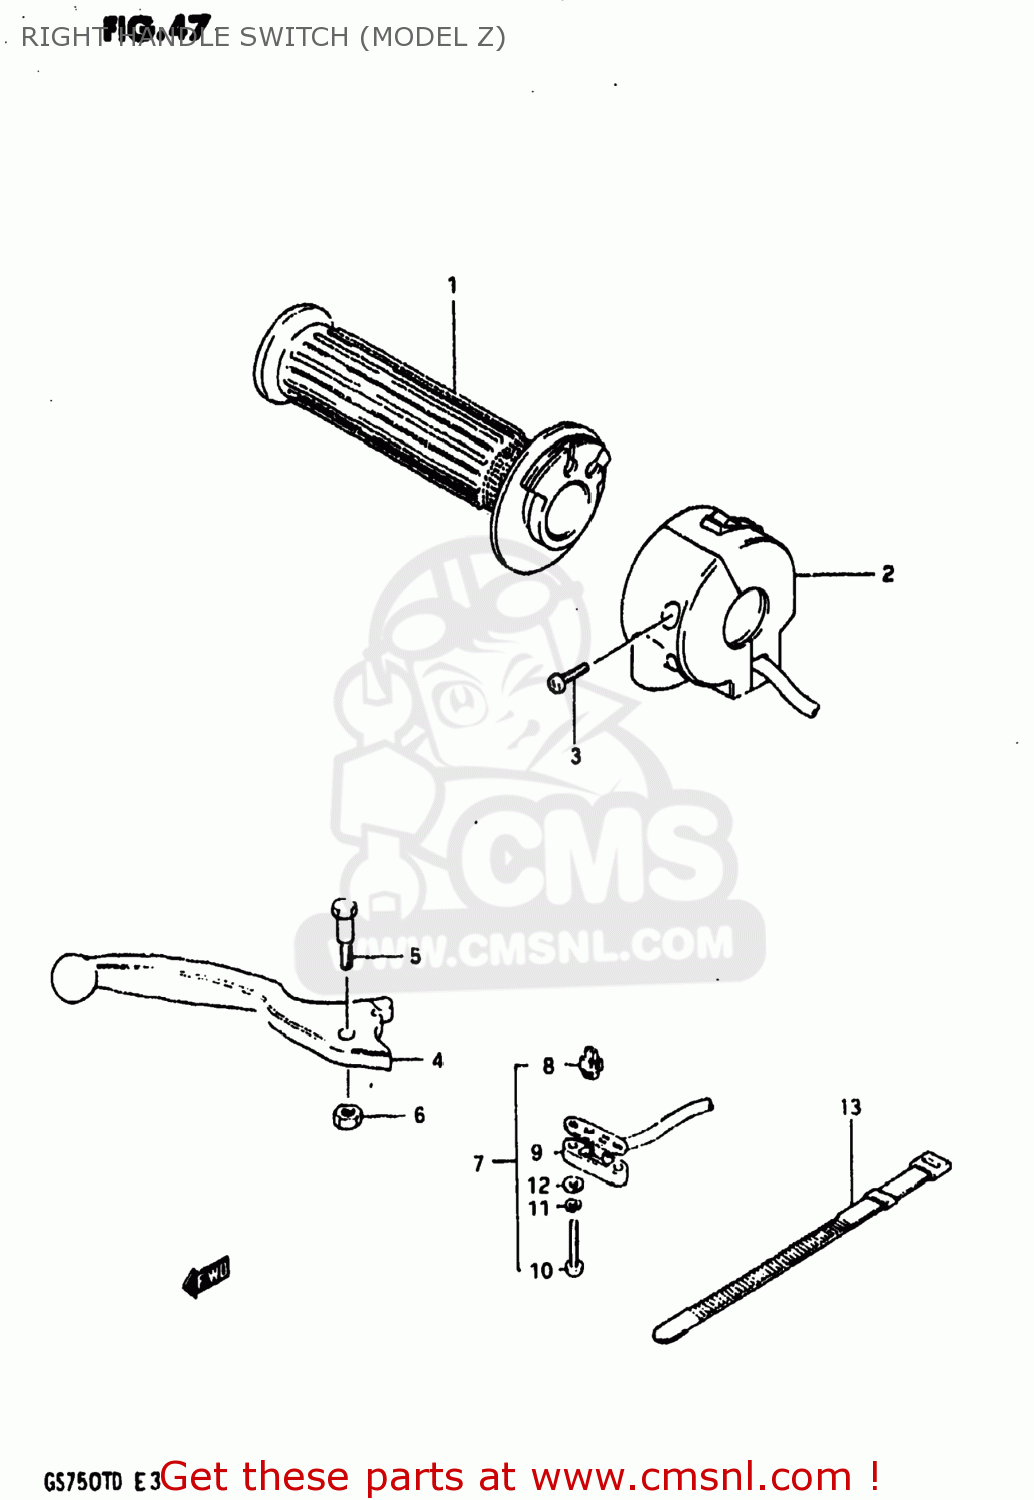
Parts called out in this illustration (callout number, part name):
1	GRIP,THROTTLE
2	SWITCH ASSEMBLY,HANDLE,RIGHT
3	SCREW
4	LEVER,BRAKE
5	BOLT
6	NUT 6MM
7	SWITCH ASSEMBLY
8	CONTACT,SWITCH
9	COVER,FR BK TERMINAL BASE
10	SCREW
11	LOCK WASHER
12	WASHER
13	CLAMP(L:120)
14	BUTTON,STARTER
15	SPRING,STARTER BUTTON
16	CONTACT,STARTER BUTTON
